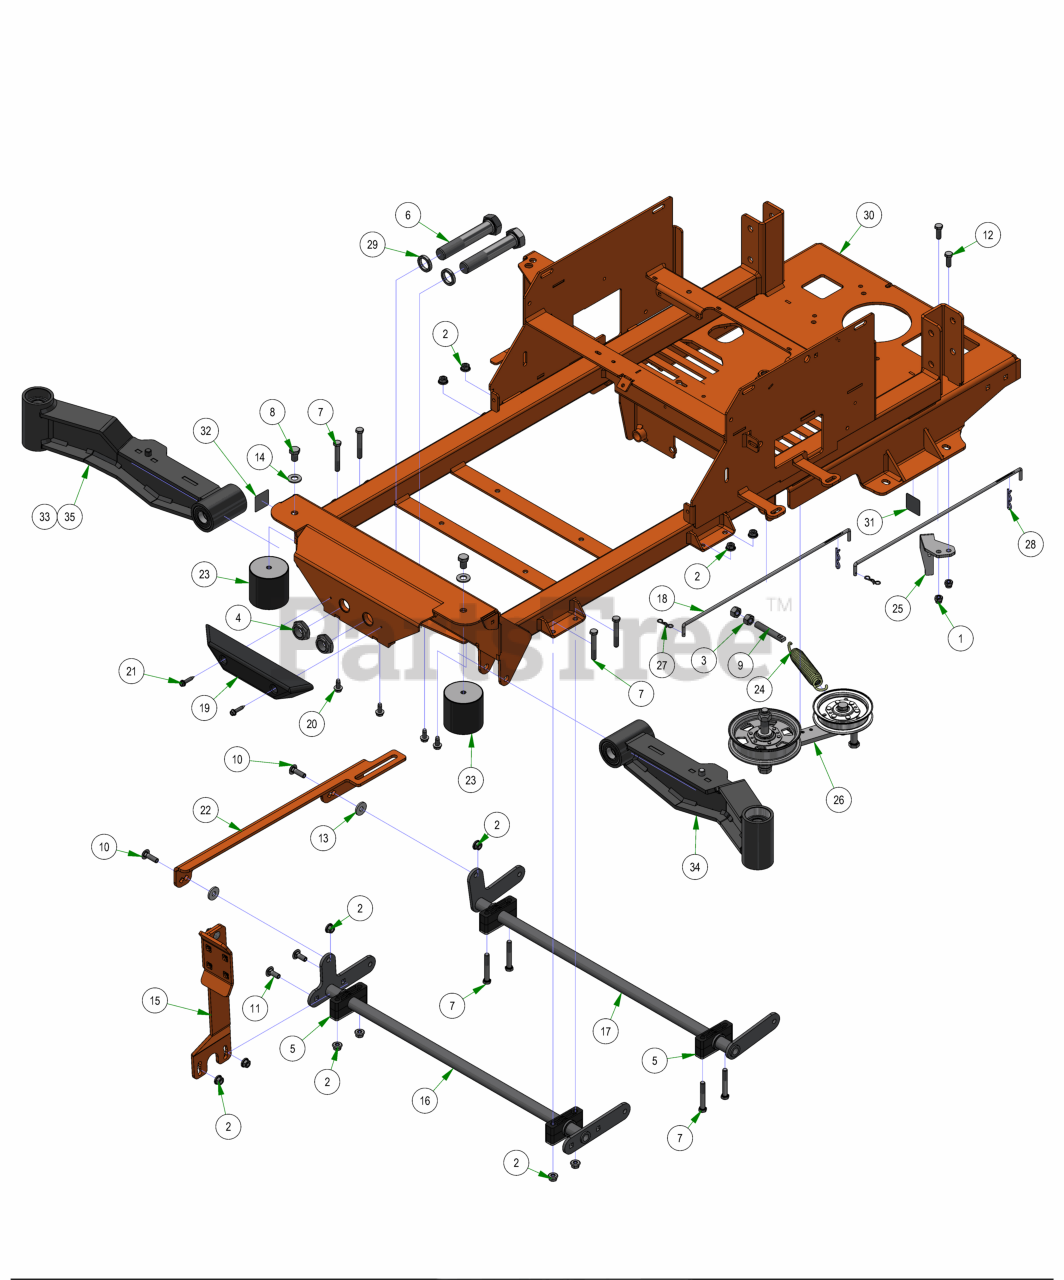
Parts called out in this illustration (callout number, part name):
1	3/8-16 NYLON INSERT LOCKNUT ZINC
2	3/8-16 NYLON INSERT FLANGE LOCKNUT (GR.F) ZINC
3	1/2-13 HEX NUT ZINC
4	1"-14 NYLON INSERT JAM LOCKNUT ZINC
5	Pillow Block Kit
6	1"-14 X 5-1/2 HEX CAP SCREW (GR.8) ZINC YELLOW
7	3/8-16 X 2-1/2 HEX CAP SCREW (GR.5) ZINC
8	1/2-13 X 3/4 HEX CAP SCREW (GR.5) ZINC
9	All Thread
10	3/8-16 X 1-1/4 CARRIAGE BOLT ZINC
11	3/8-16 X 1 CARRIAGE BOLT (GR.5) ZINC
12	3/8-16 X 1 GR 5 Hex Bolts Zinc
13	.390 ID X 1.12 OD X .125 THK FLAT WASHER NYLON
14	1/2 SAE FLAT WASHER (1-1/16" OD) GR.8 ZINC YELLOW
15	Foot Pedal Assembly
16	Actuator Bar Front- 2017 MZ/ZT
17	Actuator Bar Rear- 2017 MZ/ZT
18	Neutral Rod
19	Bumper EZT
20	5/16-18 X 3/4 HEX WASHER SLOT (F) TCS ZINC
21	1/4-14 X 1-1/4 HEX WASHER UNSLOT TEK/3 ZINC
22	2017 MZ/ZT Actuator Linkage
23	Vibration Mount- Red Dot
24	Deck Idler Spring
25	2025 ZT Clutch Bracket
26	Maverick Pump Idler
28	Neutral Rod Clip
29	1.02 ID X 1.38 OD X .250 THK SPACER ZINC
30	2025 Maverick Frame
31	Patent Decal
32	Independetly Articulating Front Suspension Arms Patent Decal
33	2021 Maverick RH Short Front Suspension Arm Assy (48")
34	2021 Maverick LH Front Suspension Arm Assy (48", 54" & 60")
35	2021 Maverick RH Long Front Suspension Arm Assy (54" & 60")
